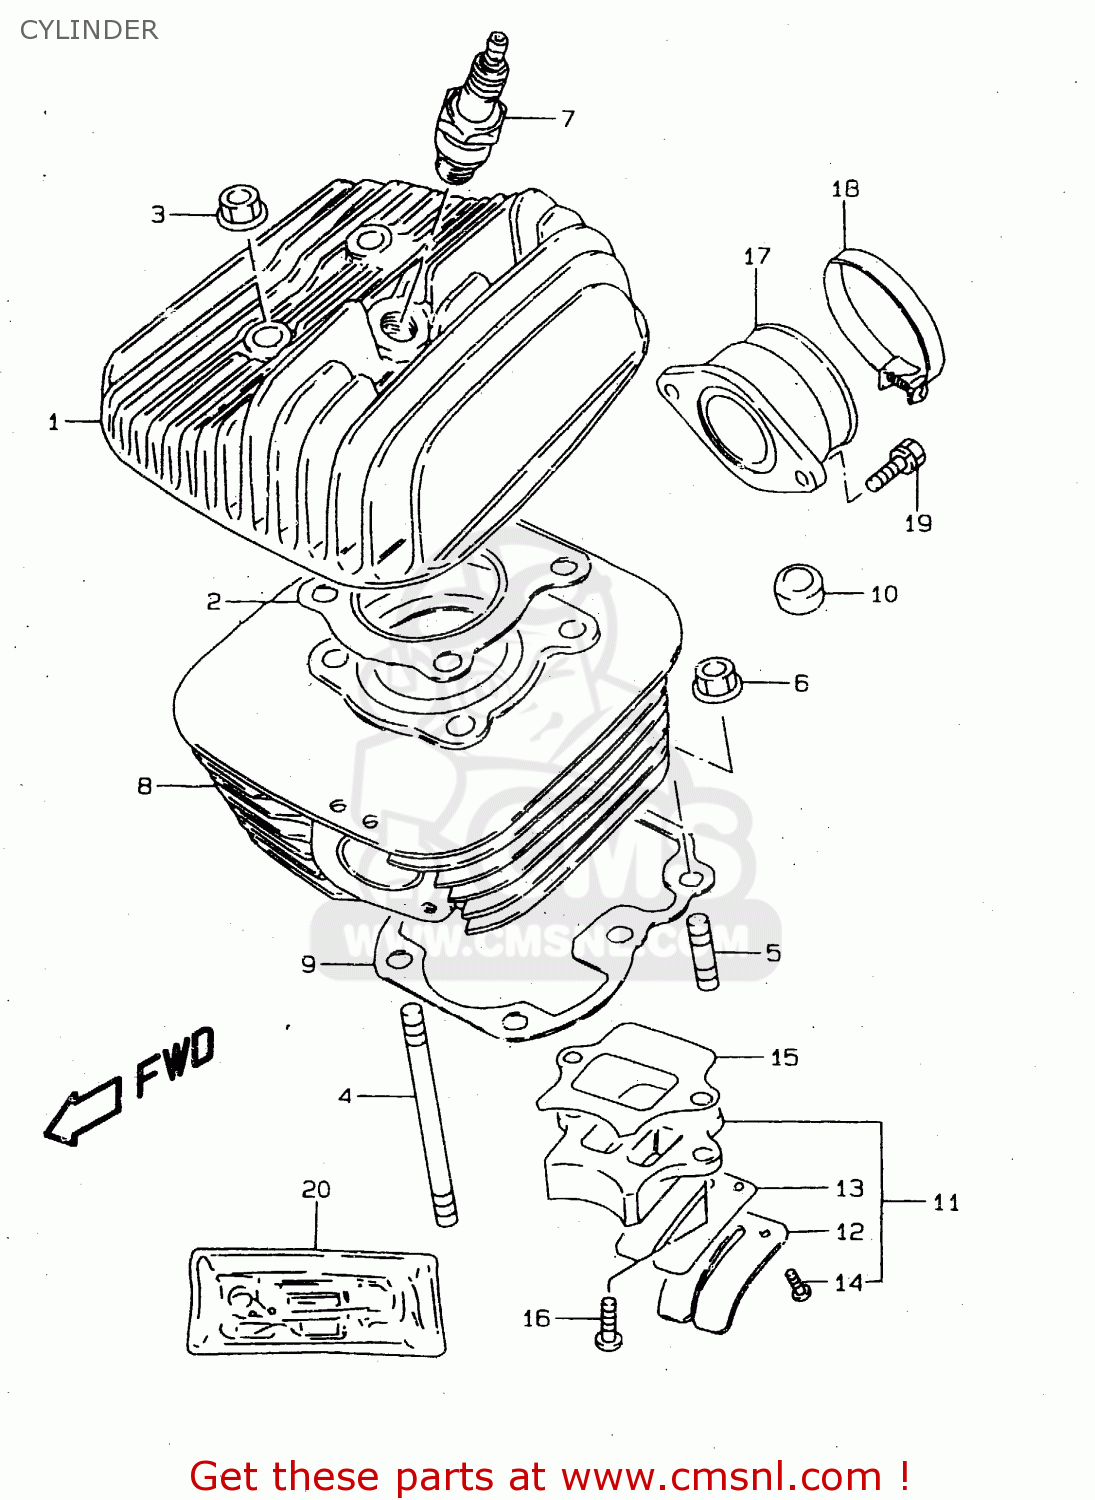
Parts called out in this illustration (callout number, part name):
1	HEAD,CYLINDER
2	GASKET,CYLINDER HEAD (NAS)
3	NUT
4	BOLT,STUD
5	STUD 6X20
6	NUT
7	SPARK PLUG B7ES
8	CYLINDER
9	GASKET,CYLINDER (NAS)
10	PAD,CYLINDER RUBBER(N1)
11	VALVE ASSY,REED
12	STOPPER,REED VALVE
13	VALVE,REED
14	SCREW
15	GASKET,REED VALVE (NAS)
16	SCREW 6X16
17	PIPE,INTAKE
18	CLAMP
19	BOLT
20	GASKET SET (NAS)
